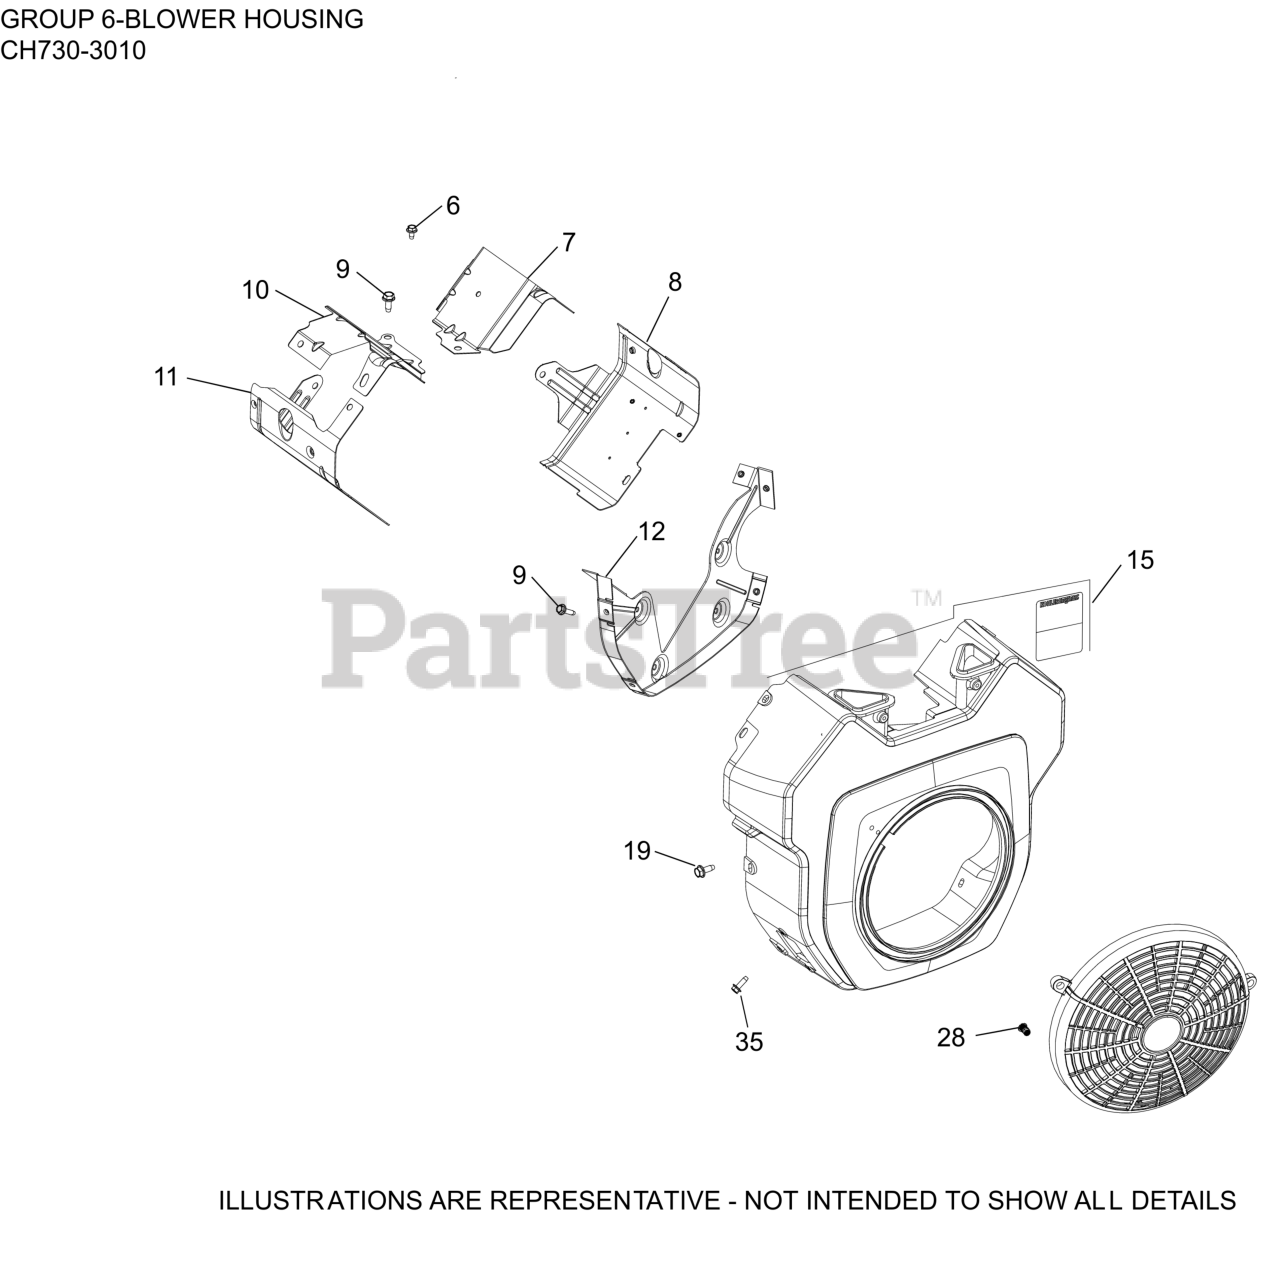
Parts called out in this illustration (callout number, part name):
6	SCREW, THREAD FORMING
7	BAFFLE, VALLEY #1 CYLINDER
8	KIT, CYL BAFFEL #1 SIDE
9	SCREW, THREAD FORMING
10	BAFFLE, VALLEY #2 CYLINDER
11	BAFFLE, LEFT BARREL
12	KIT, BACKING PLATE
15	HOUSING, BLOWER
15	KIT, BLOWER HOUSING
19	SCREW, THREAD FORMING
28	INSERT, THREADED (M5)
35	SCREW, THREAD FORMING
